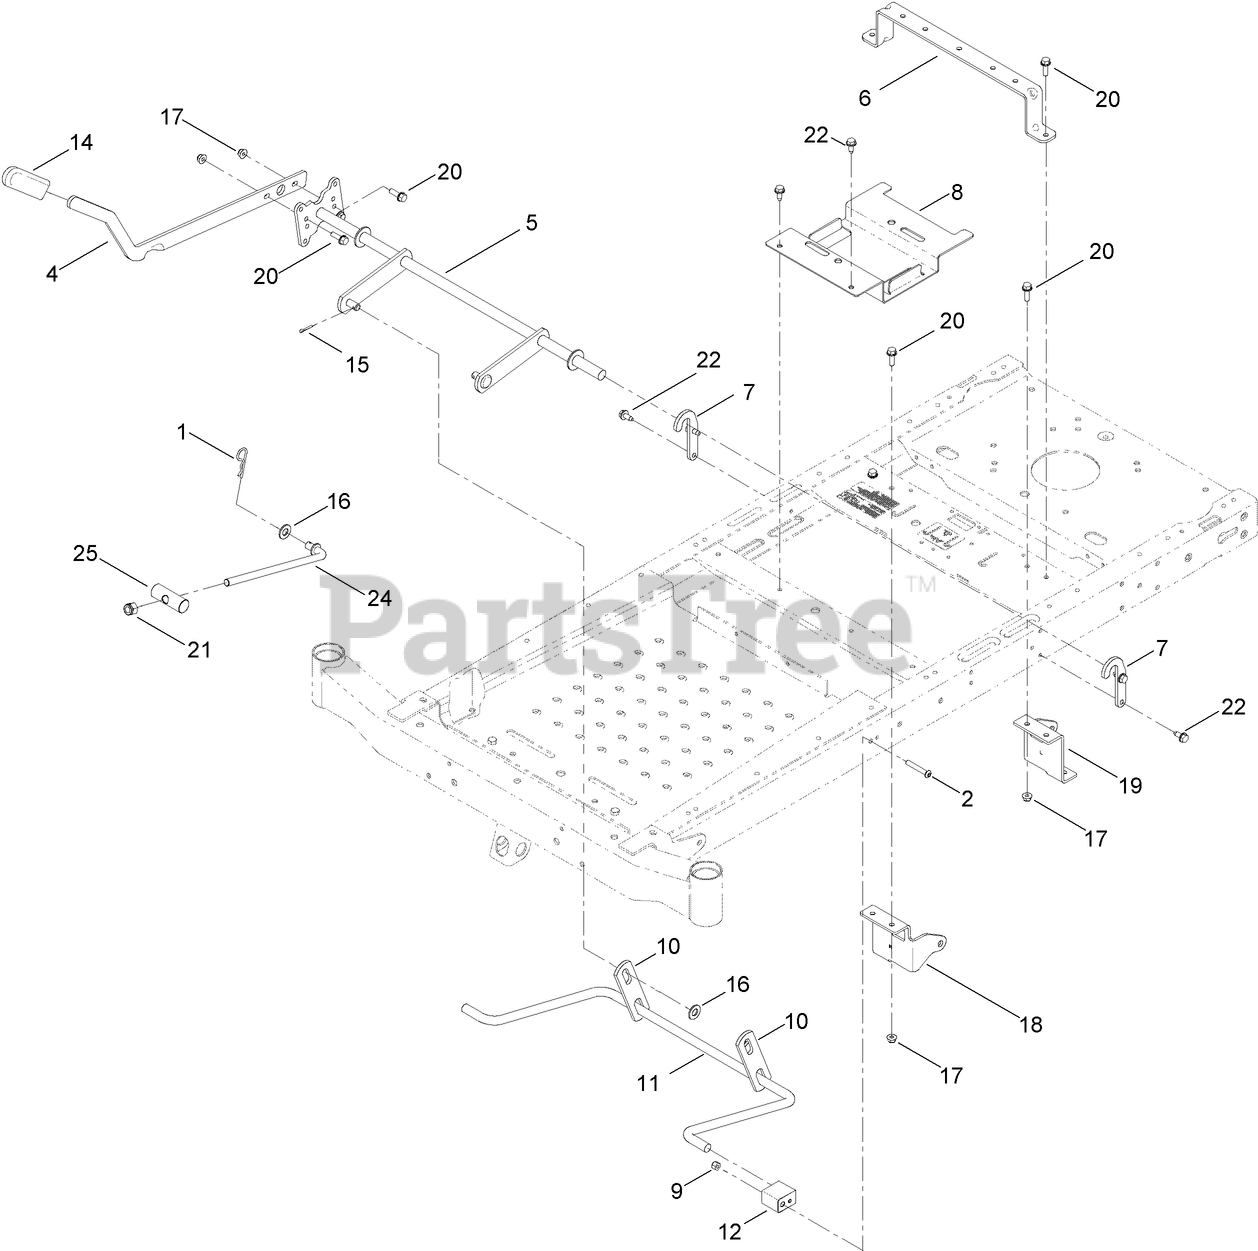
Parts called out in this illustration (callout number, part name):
1	PIN-COTTER
2	SCREW-HSBH
4	LEVER-LIFT
6	BRACE-SEAT, REAR
7	BRACKET-LIFT
8	BRACKET-BATTERY
9	NUT-LOCK, NI
10	LINK-LIFT
11	ARM-LIFT, REAR (WIDE)
12	BLOCK-PIVOT
14	GRIP-LEVER
15	PIN-COTTER
16	WASHER-FLAT
17	NUT-HF, NI
18	MOUNT-HYDRO, FRONT (RH)
20	SCREW-HHF
21	NUT-HEX
22	SCREW-HWHTF
25	PIN-PIVOT
